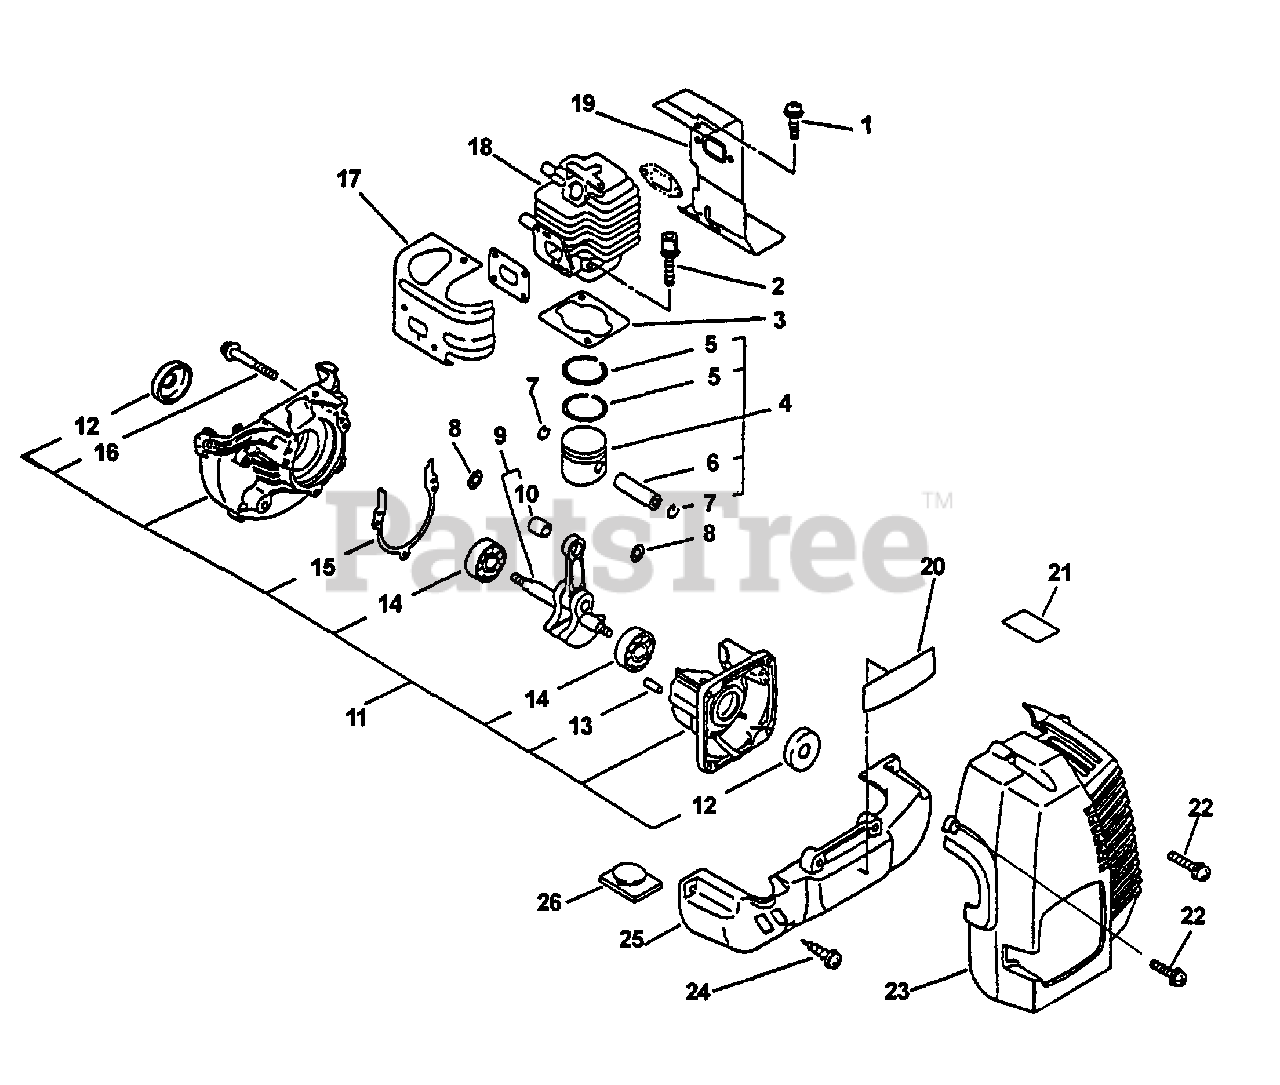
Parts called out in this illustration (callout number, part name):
1	SCREW - 5X10
2	SCREW - 5X22
3	GASKET, CYLINDER
4	PISTON KIT
5	RING, PISTON
6	PIN, PISTON
7	RING, RETAINING
8	SPACER, PISTON
9	CRANKSHAFT ASSY
10	BEARING, NEEDLE
11	CRANKCASE KIT
12	SEAL, OIL
13	PIN - LOCATING
14	BEARING, BALL - 6201
15	GASKET, CRANKCASE
16	SCREW - 5X28
17	COVER, CYLINDER - INTAKE
18	CYLINDER
19	COVER, CYLINDER - EXHAUST
20	LABEL - MODEL
21	LABEL - HOT SURFACE
22	SCREW - 5X16
23	COVER, ENGINE
24	SCREW - 5X20 -- TAPPING
